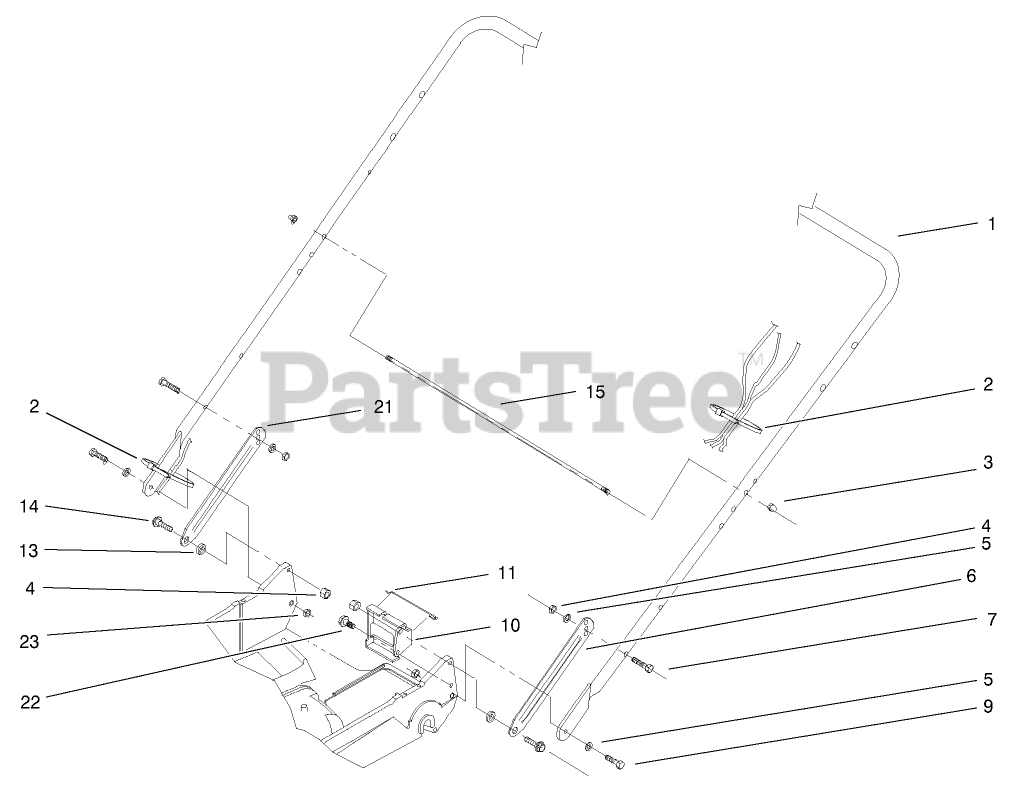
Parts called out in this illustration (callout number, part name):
2	TIE-CABLE
3	NUT-CAP
4	NUT-LOCK, NI
5	WASHER-BELLEVILLE
6	LATCH-HANDLE, LH
7	SCREW-HH
9	SCREW-HH
10	BRACKET-ADJUSTMENT, TRACTION
11	RETAINER-CABLE
13	SPACER
14	SCREW-SHOULDER
15	ROD-SUPPORT, BAG
21	LATCH-HANDLE, RH
22	SCREW-HWHTF
23	NUT-LOCK, NI
